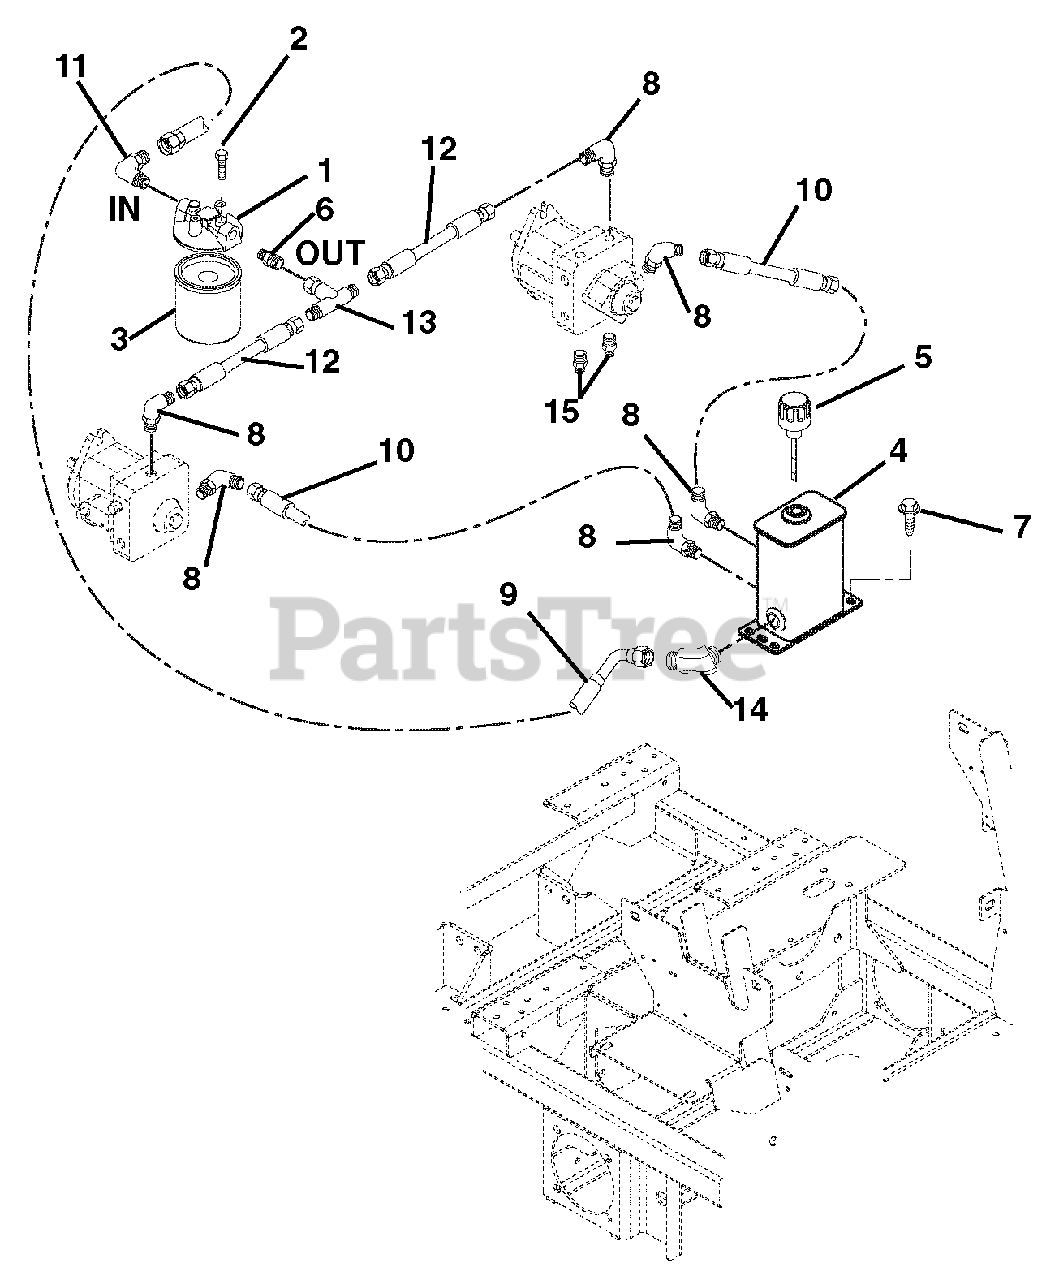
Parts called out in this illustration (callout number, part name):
1	HEAD, FILTER
2	BLT-HEX .25-20X.50 GR5 EPOXY
3	FILTER ELEMENT, ZINGA AE-25
4	WMT,FORMED HYD.TANK-3 PORT
5	BREATHER, DIPSTICK
6	ADPTR,FACE SEAL 8X8 1/2 O-RING
7	@SCR-TAP .38-16X.75 HWH TR YWZ
8	FTG. HYD. 90 EL M8F-M8O
9	HOSE, HYD. .50-19-0K F8F0-F8F9
10	HOSE,HYD..50-10-0K FO8J0-FO8JO
11	FTG. HYD. 90 EL M8F-M8O
12	HOSE,HYD. .50-5-0K FO8J0-FO8J0
13	FTG.HYD TEE M8O-F8O-F8O
14	FTG,HYD 45DEG M8F-M80
15	FITTING, HYD (4 F5OLO)
